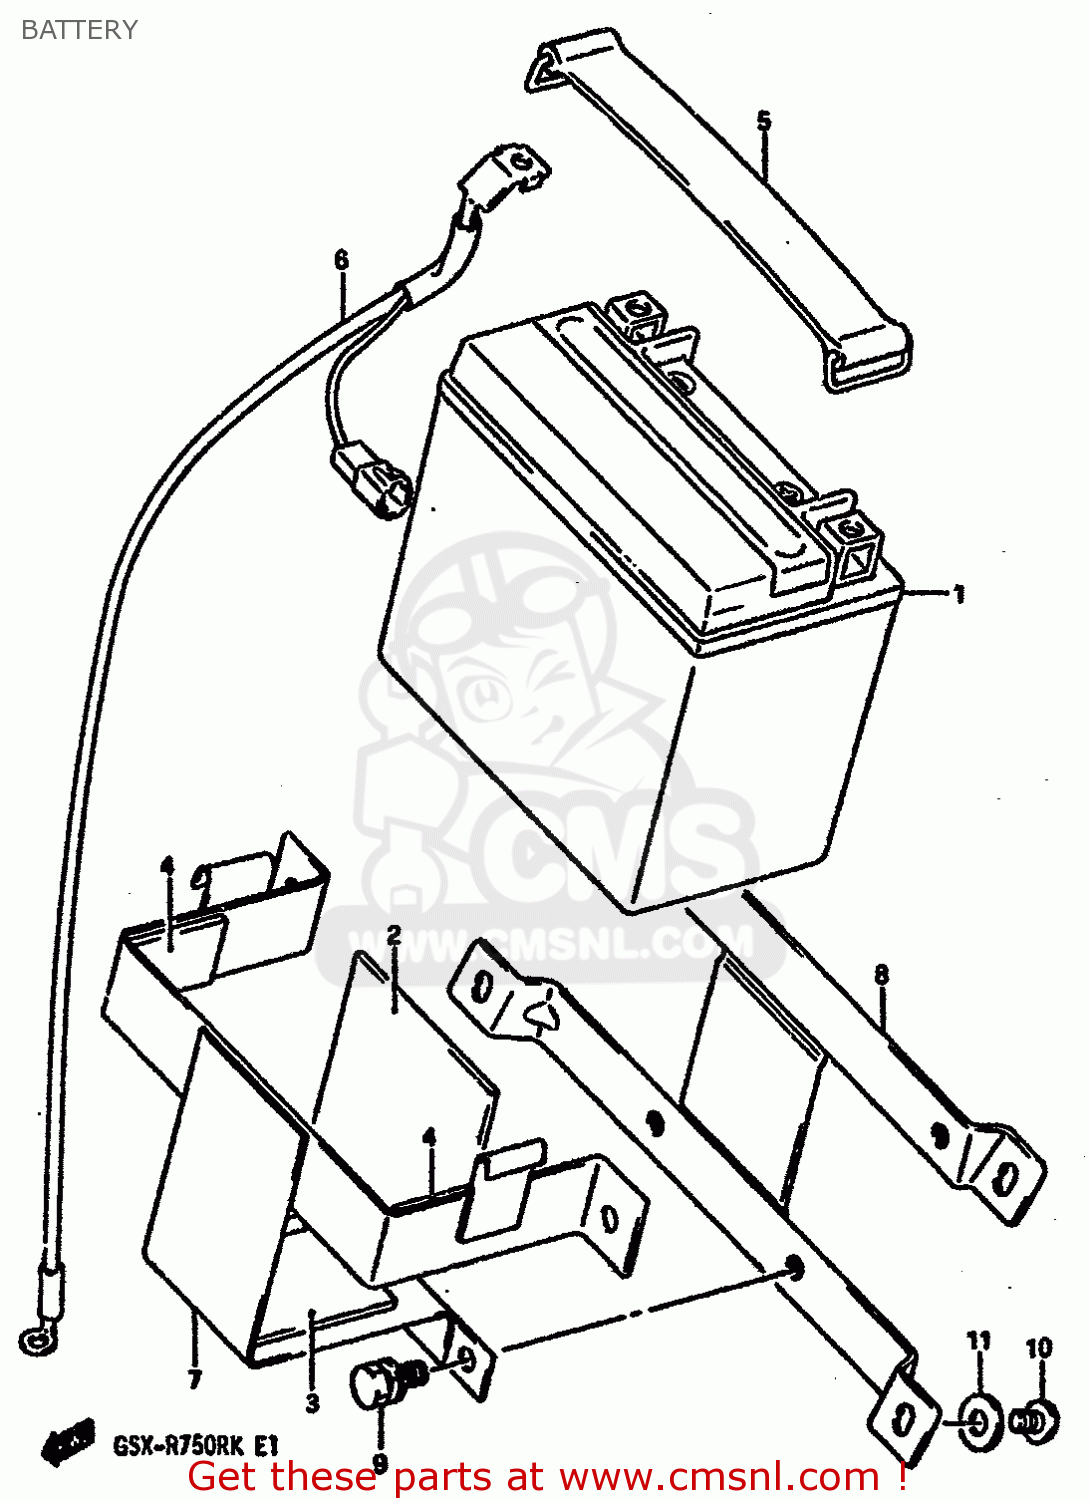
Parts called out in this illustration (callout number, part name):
1	BATTERY (YTX12-BS,12V,10AH)
2	PROTECTOR(80X80X2)
3	PROTECTOR,BATTERY
4	PROTECTOR(170X95X3.0)
5	BAND
6	LEAD WIRE (-)
7	HOLDER,BATTERY
8	BRACKET
9	BOLT
10	SCREW 6X12
11	WASHER
